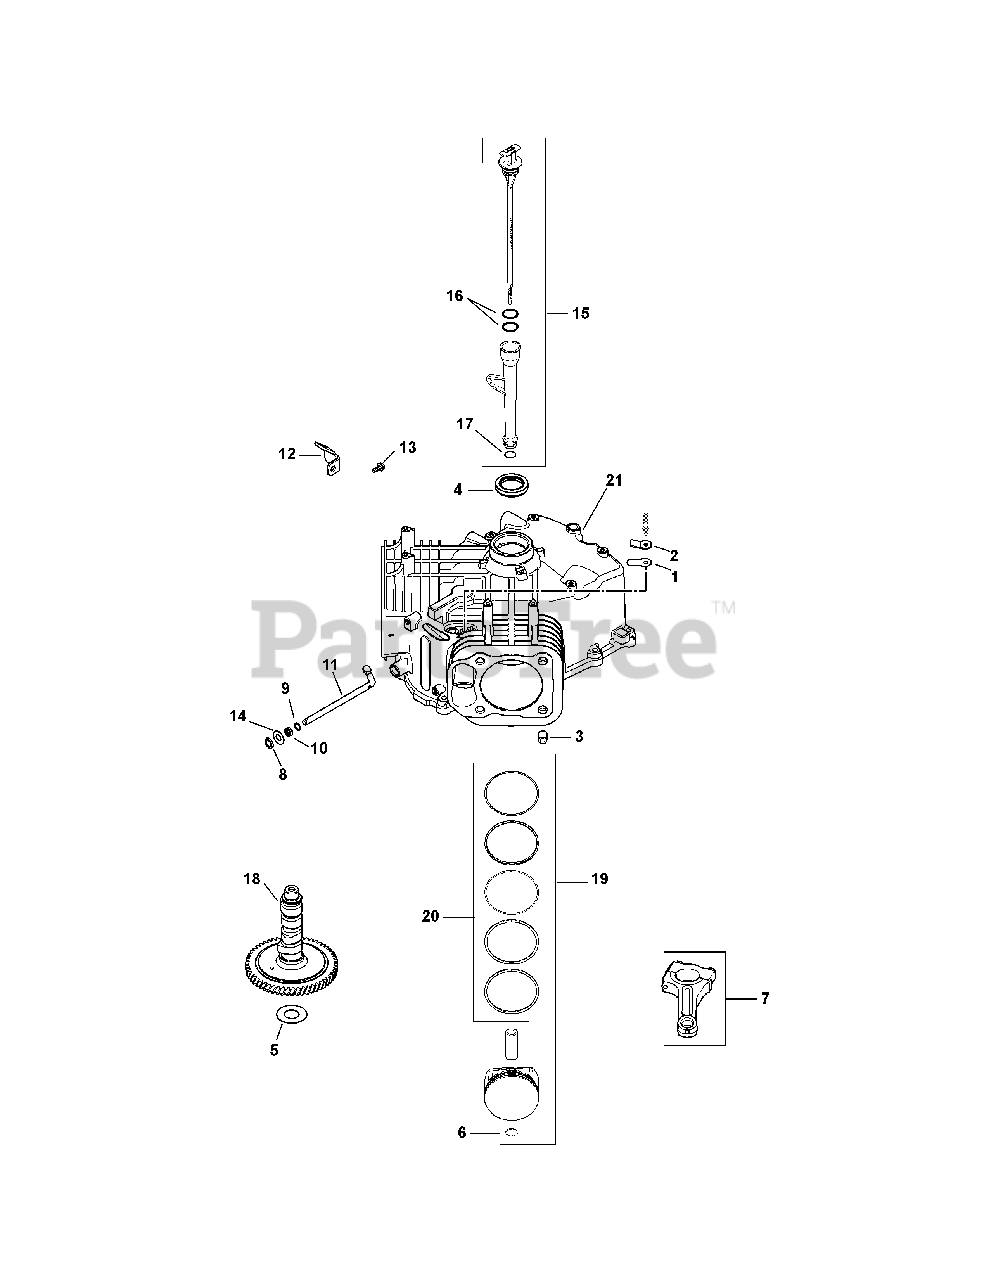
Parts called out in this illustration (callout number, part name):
1	Breather Reed
2	Breather Reed Retainer
4	Oil Seal, 1.78 x 1.26
5	Camshaft Shim (White, .028)
5	Camshaft Shim (Blue, .03)
5	Camshaft Shim (Red, .032)
5	Camshaft Shim (Yellow, .034)
5	Camshaft Shim (Green, .036)
5	Camshaft Shim (Gray, .038)
5	Camshaft Shim (Black, .04)
6	Piston Pin Retainer
7	Connecting Rod (STD)
8	Ring Retainer
9	Flat Washer, 11/32
10	Governor Cross Shaft Seal
11	Governor Cross Shaft
12	Oil Fill Tube Bracket
13	Flange Screw, M5 x .8 x 13
14	Flat Washer, 9mm
15	Dipstick & Tube Kit
17	Lower Oil Fill Tube O-Ring
18	Camshaft Assembly
19	Piston Kit w/ Ring
19	Piston Kit w/ Ring (0.25) 83mm
19	Piston Kit w/ Ring (0.08) 83mm
20	Ring Set, Piston STD
20	Ring Set, Piston (.08)
20	Ring Set, Piston (.25)
21	Crankcase (Use Short Block)
